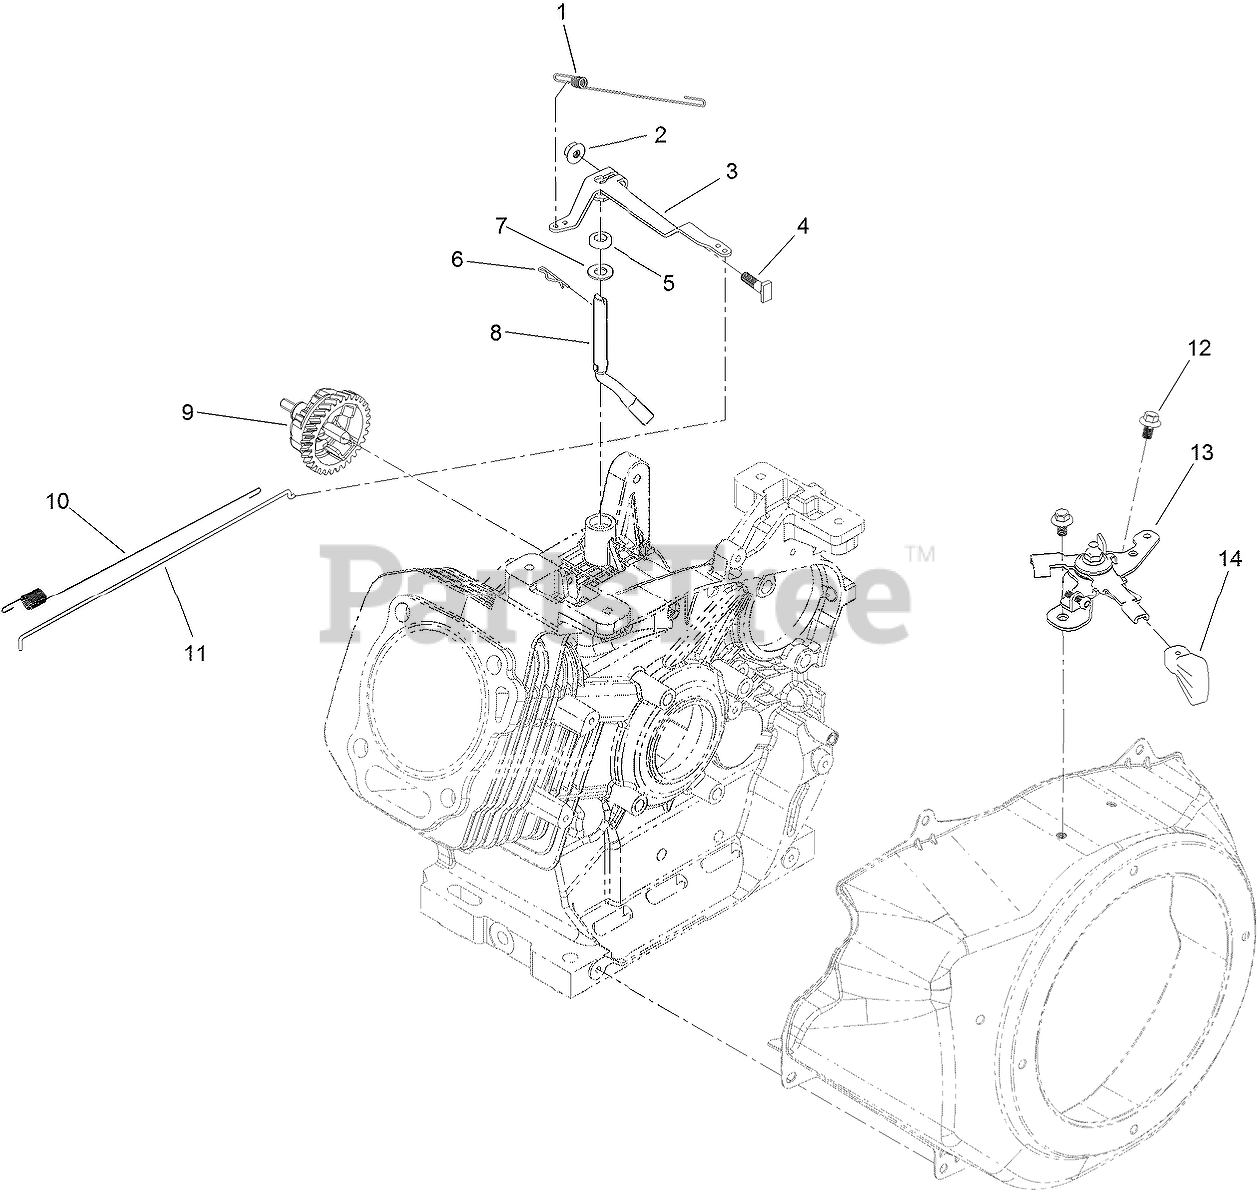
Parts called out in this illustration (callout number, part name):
1	SPRING-GOVERNOR
2	NUT-FLANGE
3	ARM-GOVERNOR
4	BOLT-ARM, GOVERNOR
5	SEAL-OIL
6	PIN-HAIR
7	WASHER-PLAIN
8	SHAFT-GOVERNOR
9	GOVERNOR GEAR ASM
10	SPRING-RETURN, THROTTLE
11	ROD-GOVERNOR
12	SCREW-HHF
13	THROTTLE CONTROL ASM
14	KNOB-CONTROL, THROTTLE
